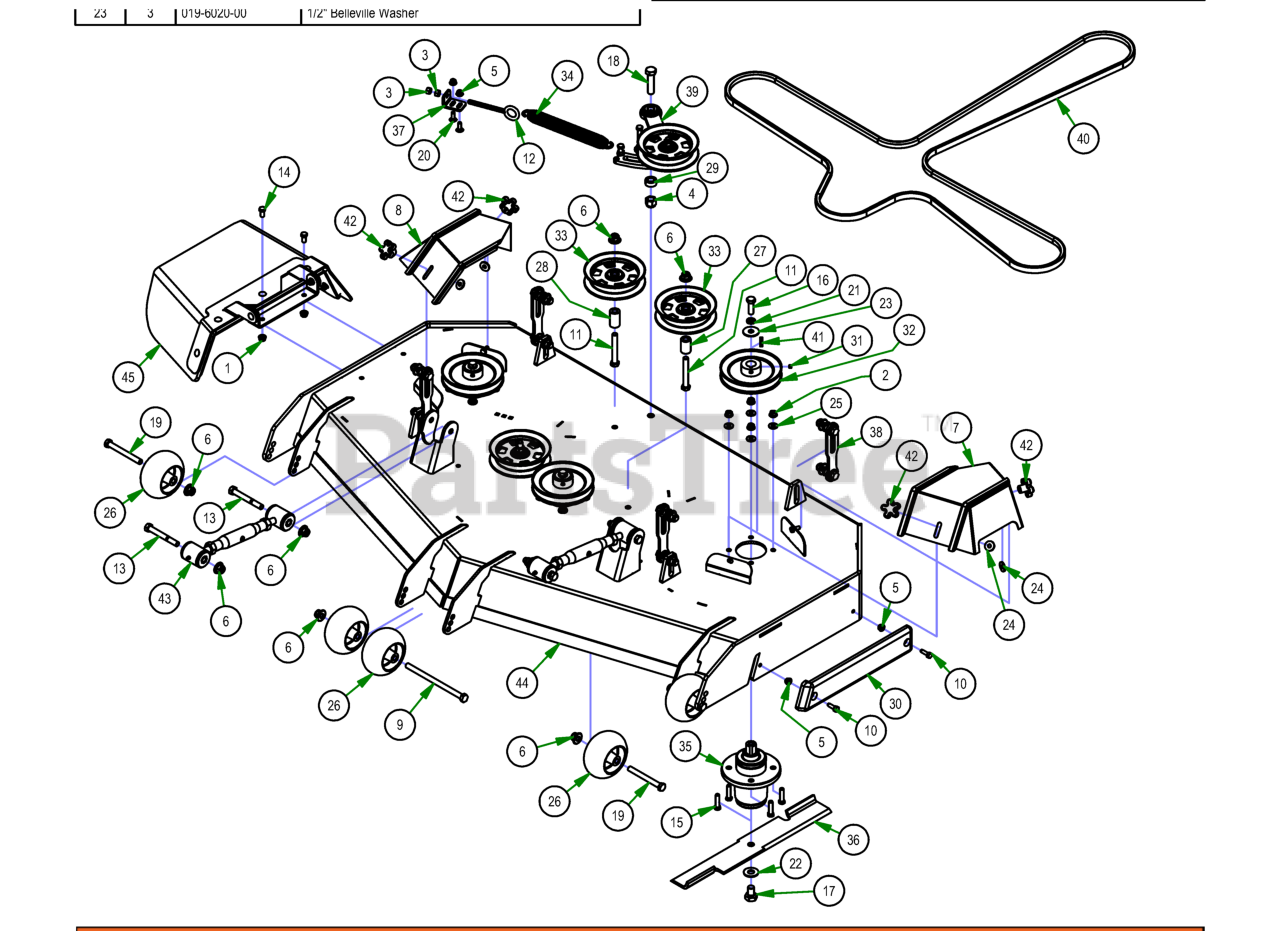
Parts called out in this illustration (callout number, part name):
1	3/8" Flange Nut
2	3/8-16 NYLON INSERT FLANGE LOCKNUT (GR.F) ZINC
3	3/8" Hex Nut
4	5/8 Std NC Nylock Nut
5	5/16" Nylon Flange Nut
6	1/2-13 NYLON INSERT FLANGE LOCKNUT ZINC
7	2019 61" Outlaw Gen2 Pulley Cover Left
8	2019 61" Outlaw Gen2 Pulley Cover Right
9	1/2-13 x 8 Hex Bolt Grade 5
10	5/16-18 x 1 GR 5 Hex Bolt Zinc
11	1/2 x 3 1/2 Flange Bolt Grade 8
12	4" 3/8-16 Eye Bolt
13	1/2" x 4" Bolt (Grade 8)
14	3/8" x 3/4" Hex Bolt
15	3/8-16 X 1-1/2 HEX CAP SCREW (GR.5) ZINC
16	1/2"-20 x 1 1/2 - Grade 5 Fine Thread Bolt
17	5/8" x 1 1/2" Grade 8 Hex Bolt (Fine)
18	5/8" x 2 1/2" Grade 5 Hex Bolt (Coarse)
19	1/2" x 4 1/2" Bolt
20	5/16" x 7/8" Carriage Bolt
21	1/2" Lock Washer
22	5/8'' Flat Washer
24	.360 ID Plastic Washer-Black
25	5/16 USS FLAT WASHER (7/8 OD) ZINC
26	2019 Deck Wheel
27	.502 ID X .750 OD X 1.500 Long Spacer
28	1 3/4" Pulley Spacer
29	5/8" x 1/" Collar W/One Set Screw
30	REVISED TRIM BUMPER_20180226
31	5/16 Set Screw
32	6 1/4" Drive Pulley
33	5-3/4 Idler Pulley
34	2019 Outlaw Gen2 Deck Spring
35	OUTLAW SPINDLE ASSEMBLY
36	61 inch Fusion Blade
37	2019 Deck Eye Bolt Tab
38	Deck Hangar Assembly
39	2019 Rebel Rogue Deck Idler
41	1/4" x 1" Key
42	5/16" Knob
43	Turnbuckle
44	2019 Sloped 61" Deck
45	2019 Outlaw Gen2 Chute Assembly
